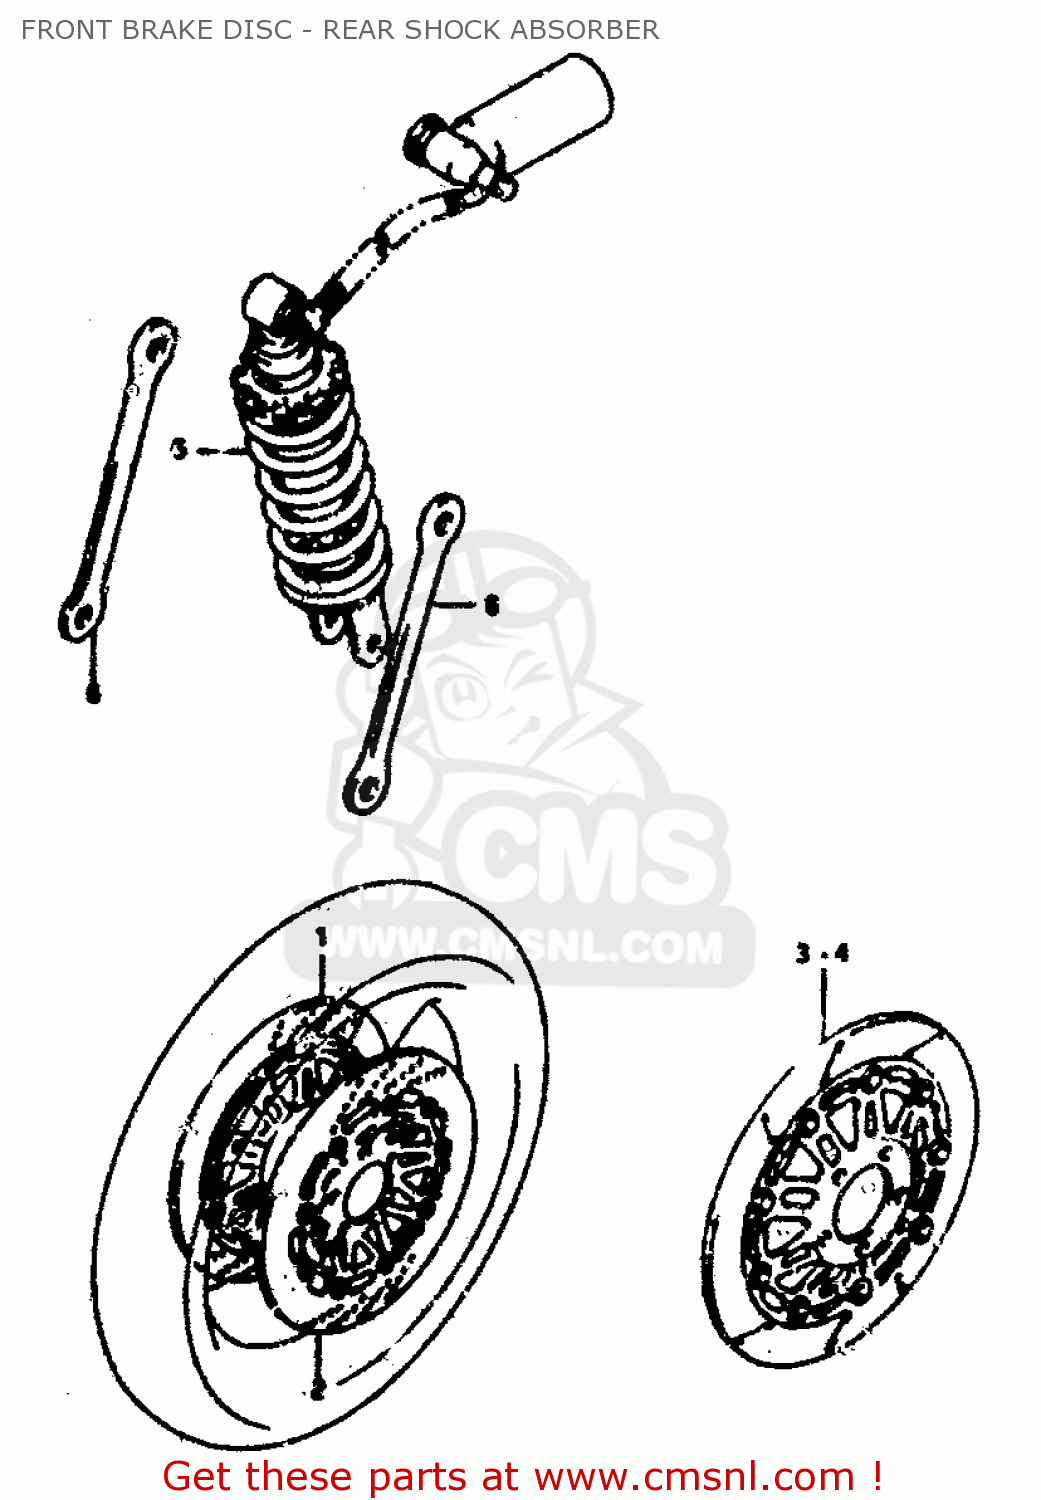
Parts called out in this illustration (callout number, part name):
1	DISC,FR BRAKE,R
2	DISC,FR BRAKE,L
3	DISC, FRONT BRAKE RH (SILVER/BLACK)
4	DISC, FRONT BRAKE LH (SILVER/BLACK)
5	ABSORBER ASSY, REAR SHOCK
6	ROD, REAR CUSHION LEVER
